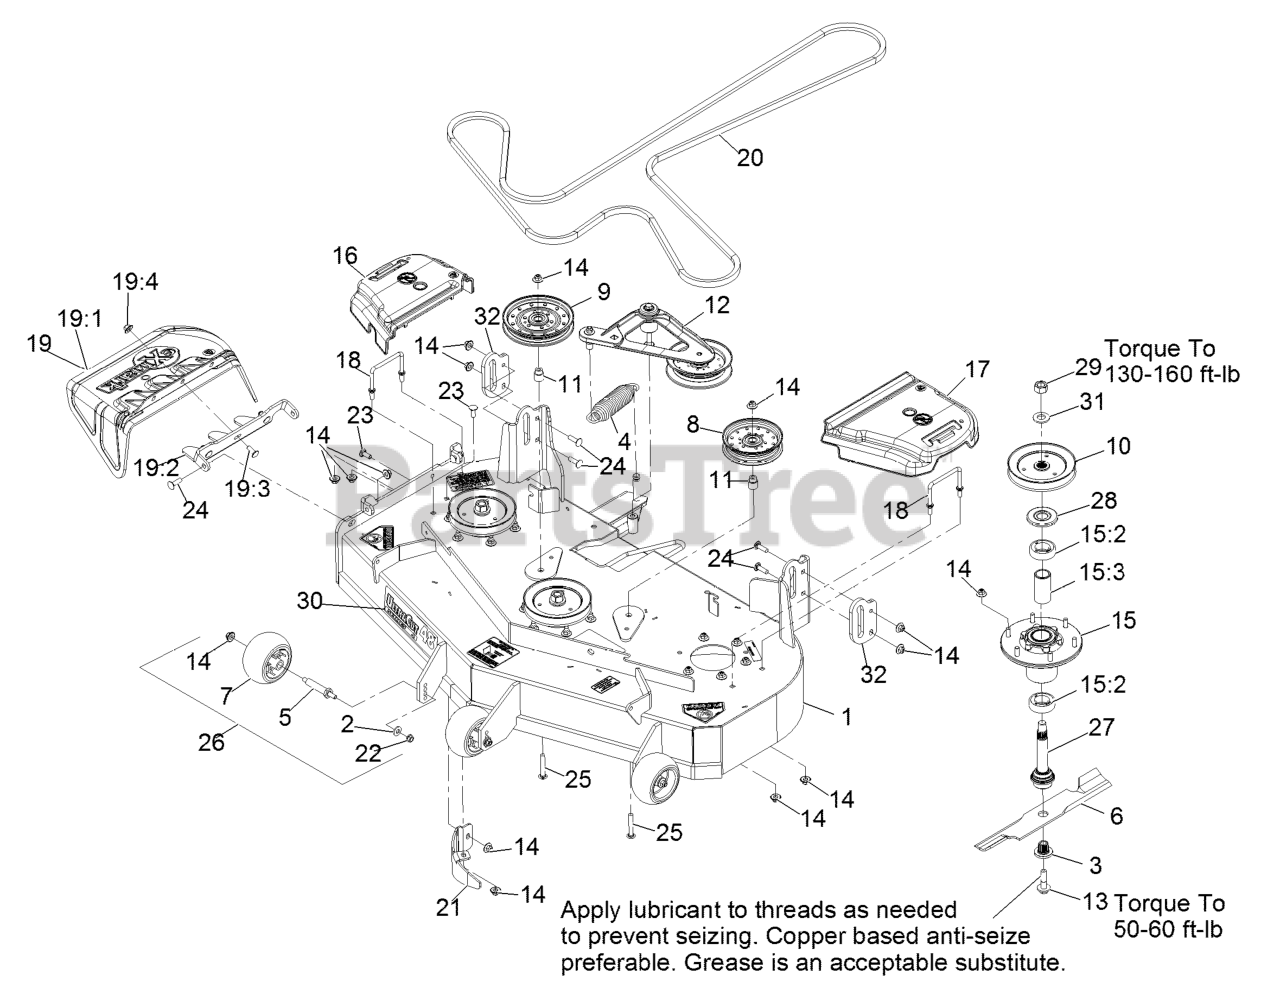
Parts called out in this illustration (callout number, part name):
1	ASM-484 DECK WITH DECALS
2	WASHER-BELLEVILLE
3	BUSHING,SPLINED
4	SPRING-EXTENSION
7	ROLLER-SCALP, ANTI
10	SHEAVE,BLADE DRIVE 5.90
11	BUSHING-IDLER
12	DECK IDLER ASM
13	SCREW,SEMS 1/2-20 X 2.19
14	Nut-Nyloc 3/8-16 Flg
15	ASM-CUTTER HSG WITH BEARINGS
15:2	BEARING-BALL
15:3	SPACER-BEARING
16	COVER-BELT, RH
17	COVER-BELT, LH
18	WIREFORM-COVER
19	ASM,DISCHARGE CHUTE
19:1	CHUTE,DISCHARGE
19:2	BRACKET,DISCHARGE CHUTE
19:3	SCREW-CARR
19:4	Nut-Nyloc 3/8-16 Flg
20	BELT
21	BAFFLE-DOGLEG,LZE48
22	NUT-HHF, WHIZ
23	SCREW-CARR
24	Bolt-Carriage 3/8-16 X 1 1/4
25	SCREW-CARR
27	ASM-SPINDLE AND SEAL
28	GUARD,BEARING TOP .989
29	NUT-HEX
30	DECAL,ULTRACUT 48 SERIES
32	PLATE-REINF, PUSH TOWER
